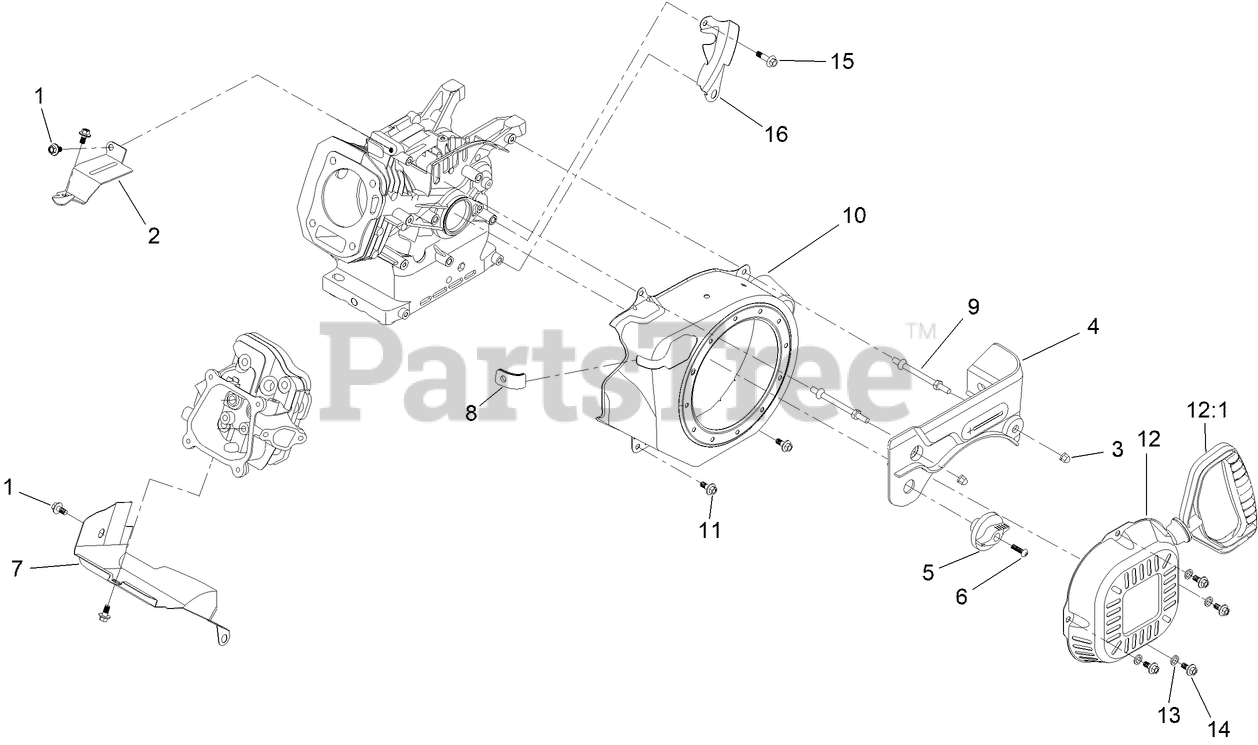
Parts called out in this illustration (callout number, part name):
1	SCREW-HHF
2	BAFFLE
3	NUT-ACORN
4	PANEL-CONTROL
5	KNOB-VALVE, FUEL
6	SCREW-BHP
7	SHROUD-LOWER
8	BLOCK-RUBBER
9	STUD-MOUNT
10	SHROUD-BLOWER
11	SCREW-HHF
12	RECOIL STARTER ASM
12:1	HANDLE-RECOIL
13	WASHER-PLAIN
14	SCREW-HHF
15	SCREW-HHF
16	SHIELD-FLYWHEEL
